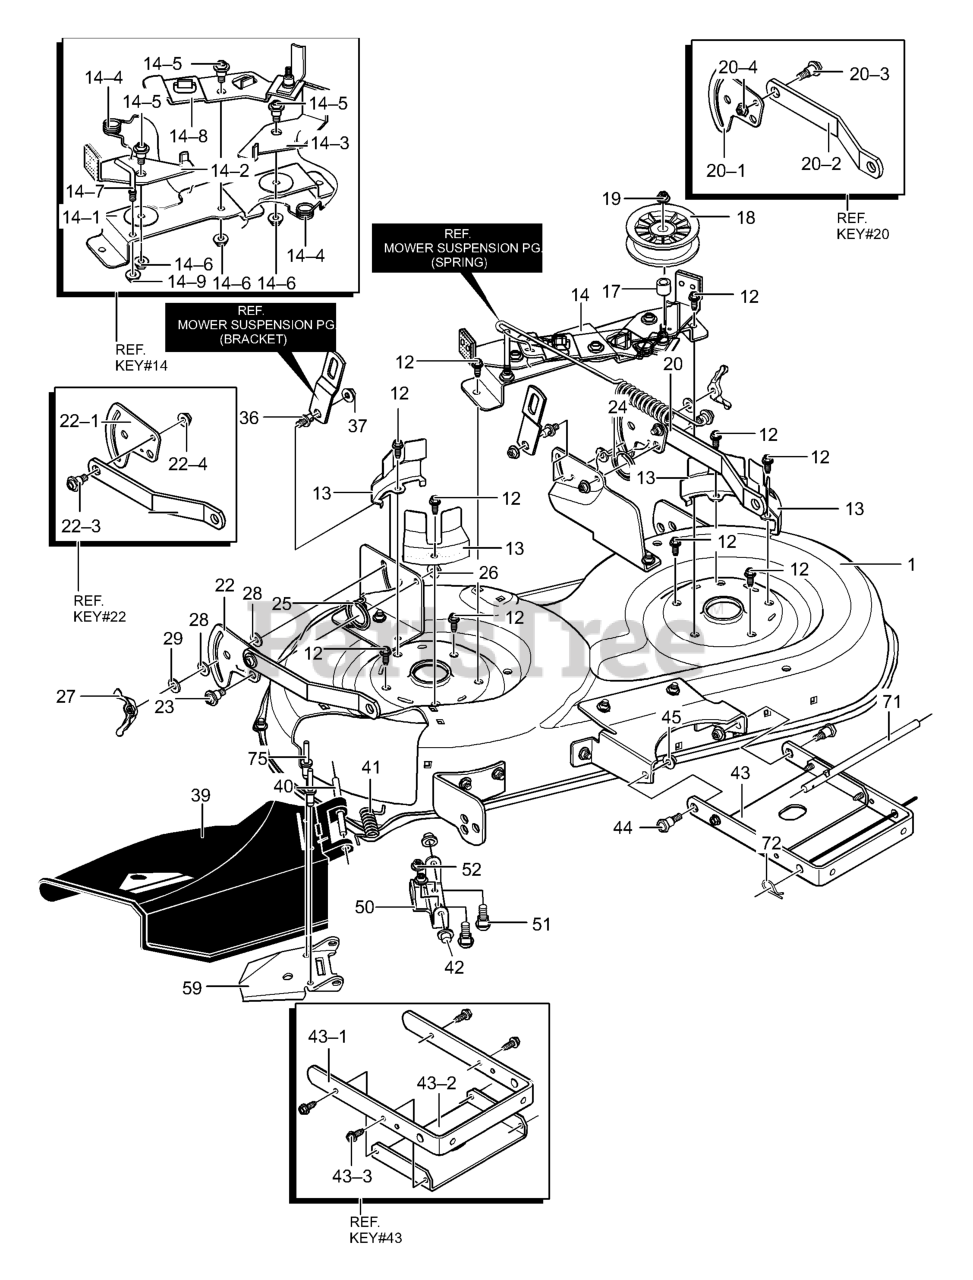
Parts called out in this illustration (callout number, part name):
1	ASSEMBLY, BLADE HOUSING
12	BOLT-3/8 X 1.25
13	COVER, BELT GUIDE
14	ASSEMBLY, IDLER BRACKET
14-1	BRACKET, BRAKE
14-2	ASSEMBLY, RIGHT BRAKE
14-3	ASSEMBLY, LEFT BRAKE
14-4	SPRING, TORSION
14-5	BOLT
14-6	NUT
14-7	SCREW, GUIDE
14-8	ASSEMBLY, IDLER ARM
14-9	NUT
17	SPACER 1/2 TO 17MM
18	PULLEY, IDLER
19	NUT, 3/8-16
20	ASSEMBLY, LEFT LIFTER
20-1	PLATE, SUSPENSION
20-2	BRACKET, SUSPENSION
20-3	BOLT, SHOULDER
20-4	NUT, FLANGE
22	ASSEMBLY, RIGHT LIFTER
22-1	PLATE, SUSPENSION
22-2	BRACKET, SUSPENSION
22-3	BOLT, SHOULDER
22-4	NUT, FLANGE
23	BOLT, SHOULDER
24	SPRING, TORSION
25	SPRING, TORSION
27	WINGNUT
28	PAD, FRICTION
29	WASHER
36	PIN, HANGER
39	DEFLECTOR, CHUTE
40	ROD, CHUTE DEFLECTOR
41	SPRING, TORSION
42	NUT, PUSH CAP
43	ASSEMBLY, STIFFENER
43-1	BRACKET, SUSPENSION
43-2	STIFFENER, DECK
44	BOLT, SHOULDER
50	BRACKET, CHUTE
51	BOLT, CARRIAGE
59	SUPPORT, DEFLECTOR
71	ROD, HANGER
72	PIN, HAIR
